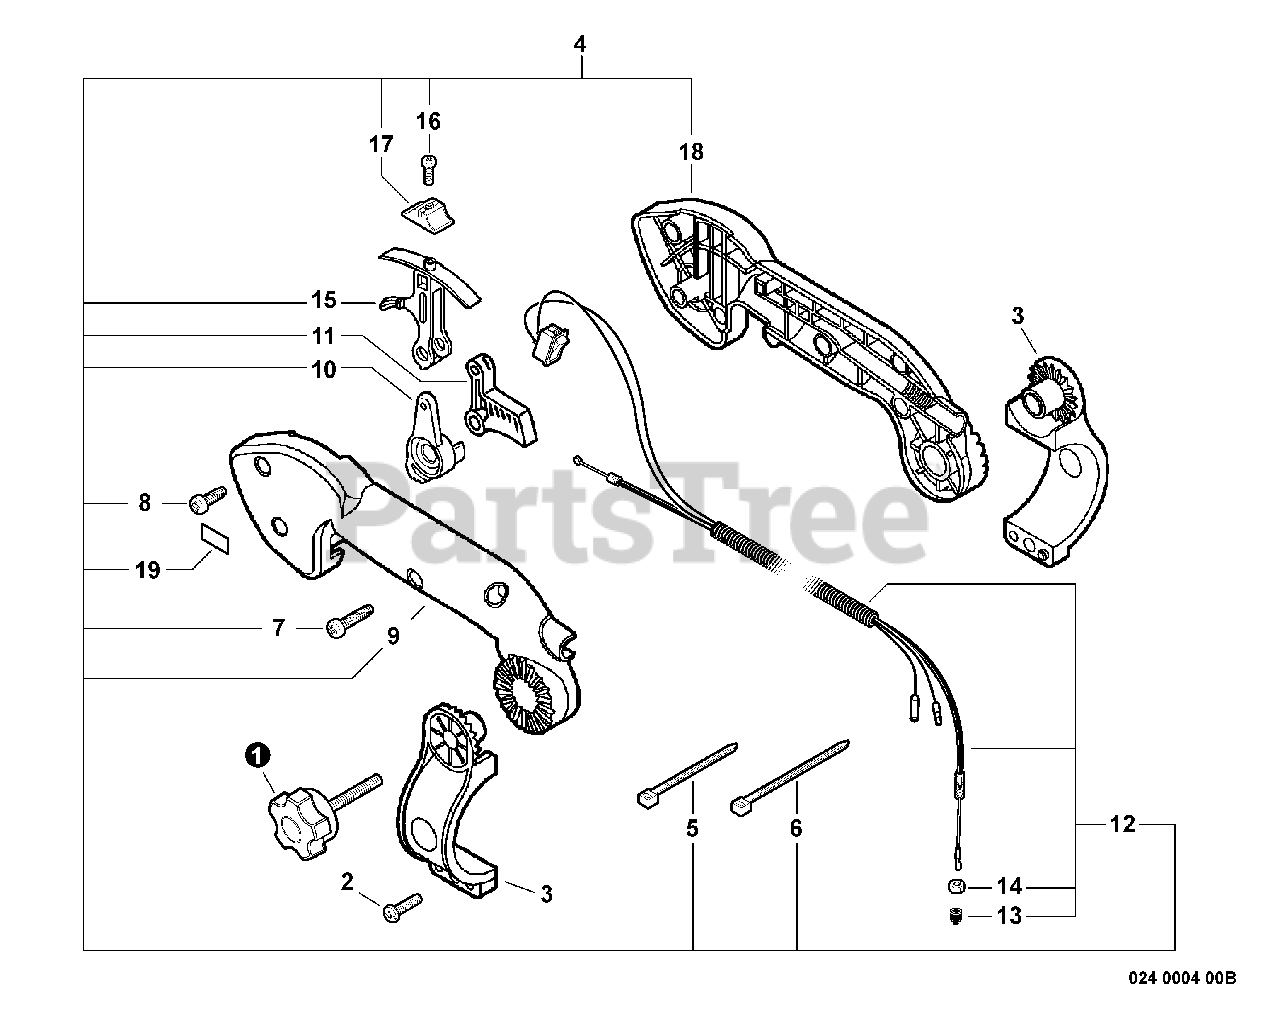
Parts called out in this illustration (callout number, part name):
1	THUMBSCREW
2	SCREW - 5X20 -- TAPPING
3	HANDLE BRACKET KIT
4	CRUISE CONTROL KIT
5	TIE, CABLE - SMALL
6	TIE, CABLE - LARGE
7	SCREW - 5X20
8	SCREW - 5
9	HANDLE, FRONT - LEFT
10	LEVER, THROTTLE
11	TRIGGER, THROTTLE
12	CONTROL CABLE ASSY
13	CAP, DUST
14	LOCKNUT - 6
15	LEVER, THROTTLE CONTROL
16	SCREW - 3X14
17	KNOB, THROTTLE CONTROL
18	HANDLE, FRONT - RIGHT
19	LABEL - IDLE
